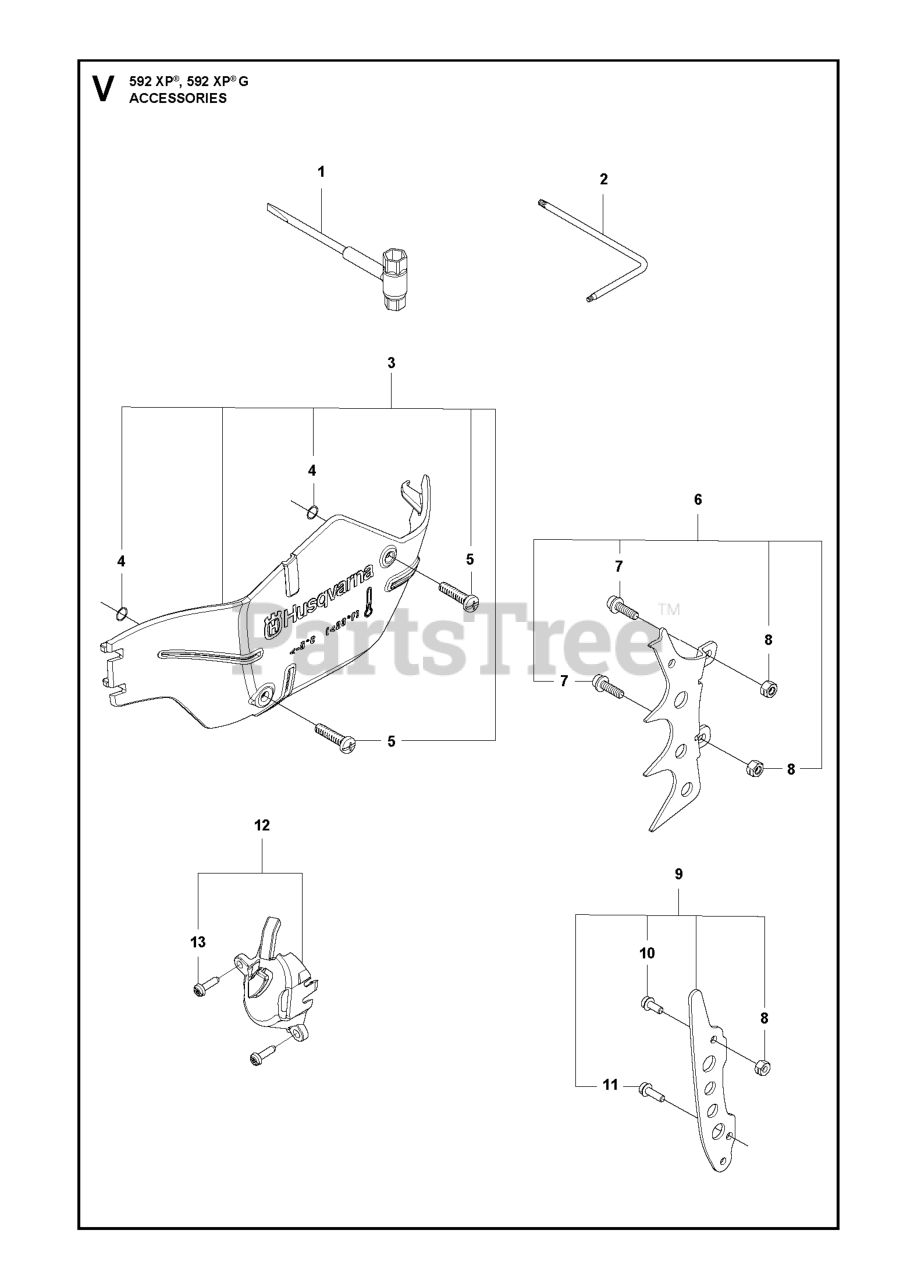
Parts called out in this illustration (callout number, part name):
1	COMBINATION WRENCH 13/16
3	WINTER KIT 585/592
6	SPIKE KIT OUTER NON-WRAP H592
9	BUMPER KIT H585/592XP/XPG
10	SCREW
12	CONNECTIVITY DEVICE KIT H592
13	SCREW CITXPANT
